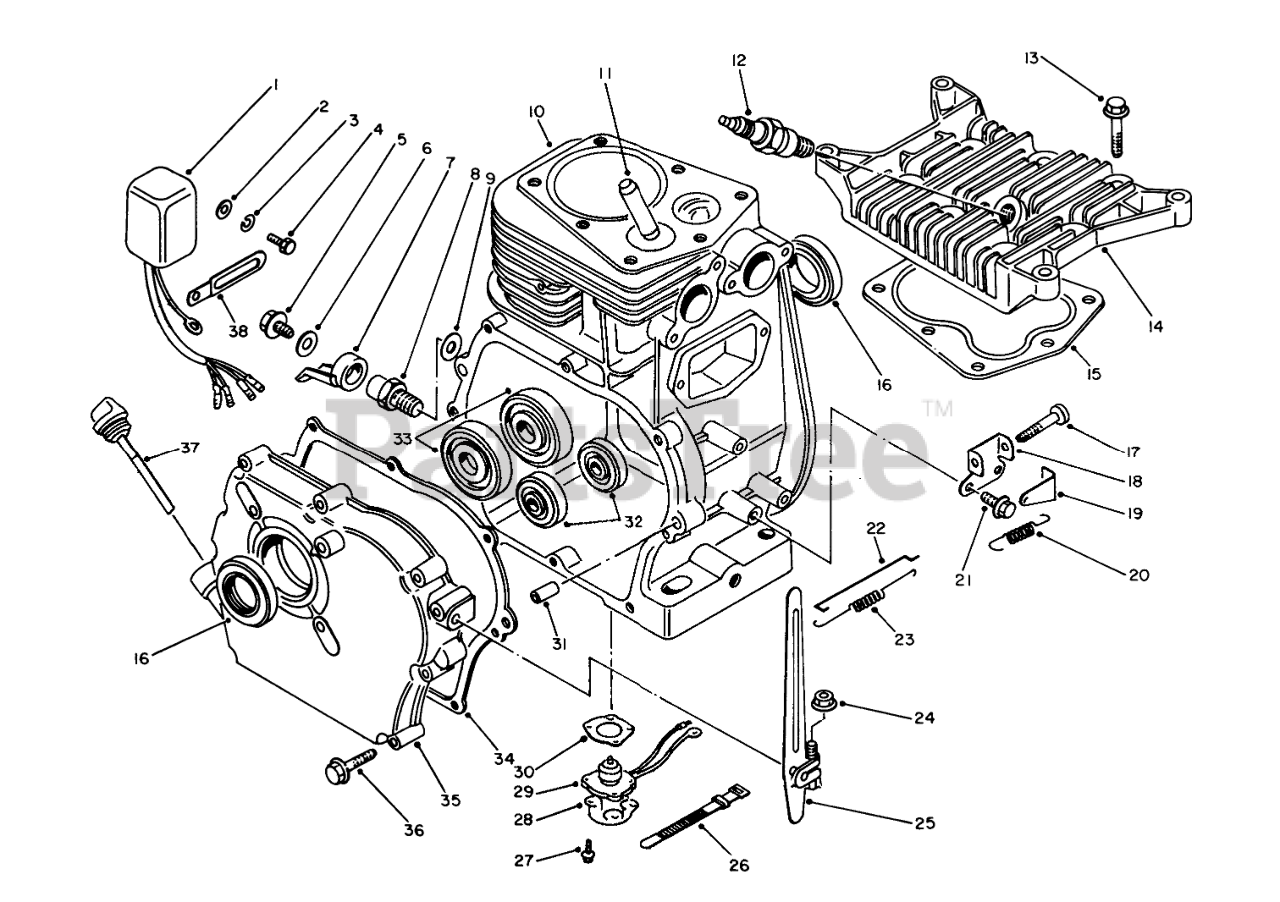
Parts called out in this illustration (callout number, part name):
1	OIL LEVEL UNIT
2	Washer
3	Lockwasher
5	Bolt
6	Gasket
7	Plate
8	Adapter
9	GASKET
10	Cylinder
11	VALVE GUIDE
12	SPARK PLUG
14	Cylinder Head
15	GASKET
16	OIL SEAL
17	Screw
18	Bracket
20	SPRING
22	Rod
23	SPRING
24	M6 X 1 LOCKNUT
25	Control Lever
26	Clamp
28	Plate
29	Sensor
30	GASKET
32	Bearing
33	Screw
34	Gasket
35	Cover
37	Gasket
38	Clamp
